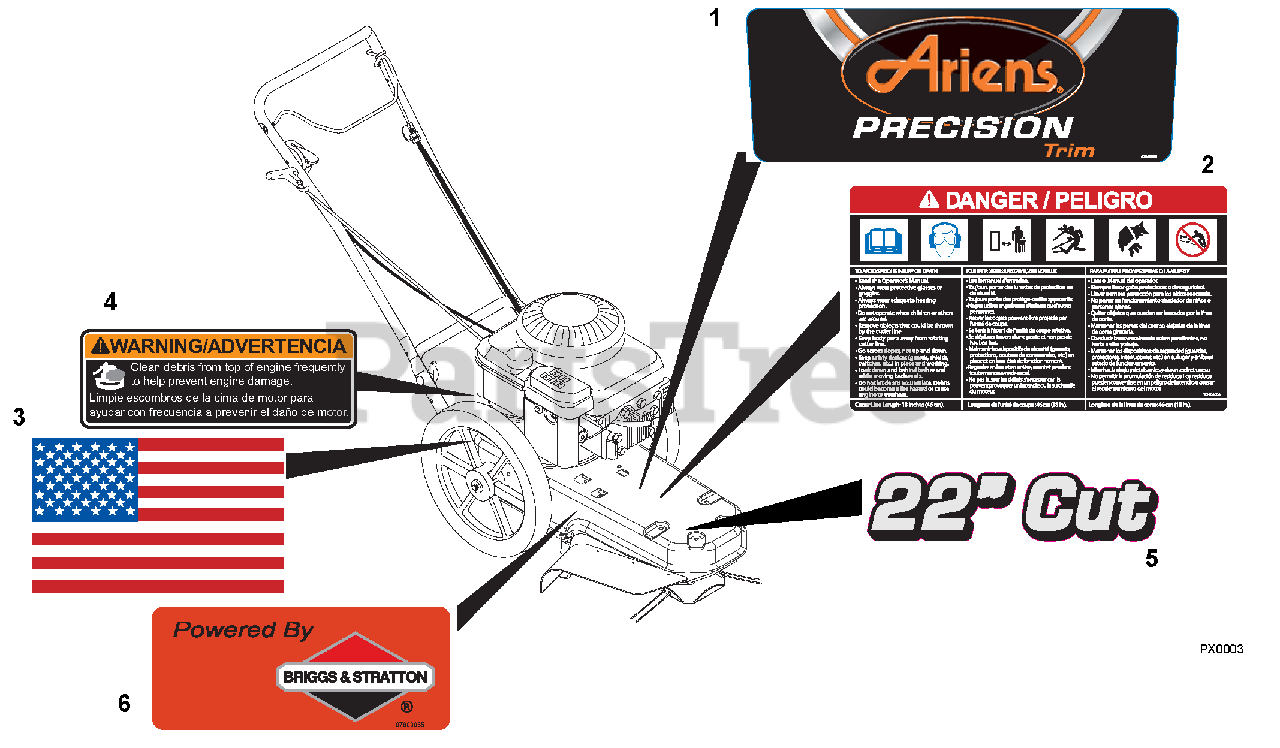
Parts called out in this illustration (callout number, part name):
1	DECAL, ARIENS PRECISION TRIM
2	DECAL - DANGER-STRING TRIMMER
3	DECAL, AMERICAN FLAG
4	DECAL, TRIMMER DEBRIS WARNING
5	DECAL, 22" CUT(STRING TRIMMER)
6	DECAL, POWERED BY B&S
